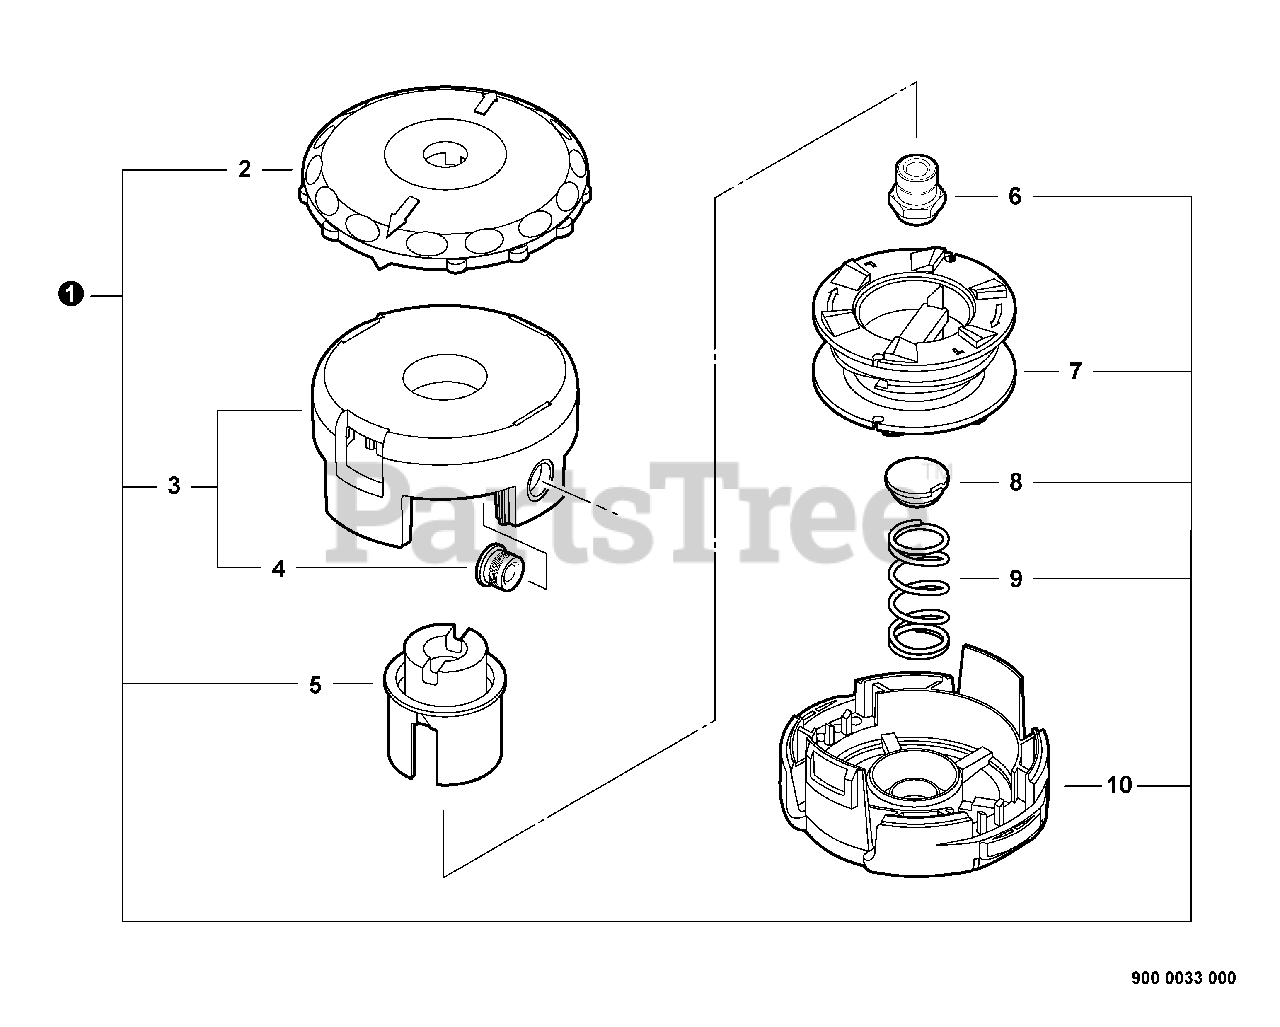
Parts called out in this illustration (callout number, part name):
1	TRIMMER HEAD, SPEED-FEED® 400
3	HOUSING ASSY, SPOOL
5	HUB (LH) BLACK
6	BUSHING M10×1.25 LH GOLD
8	CAP, SPRING
9	SPRING, GOLD
10	COVER, SPOOL
